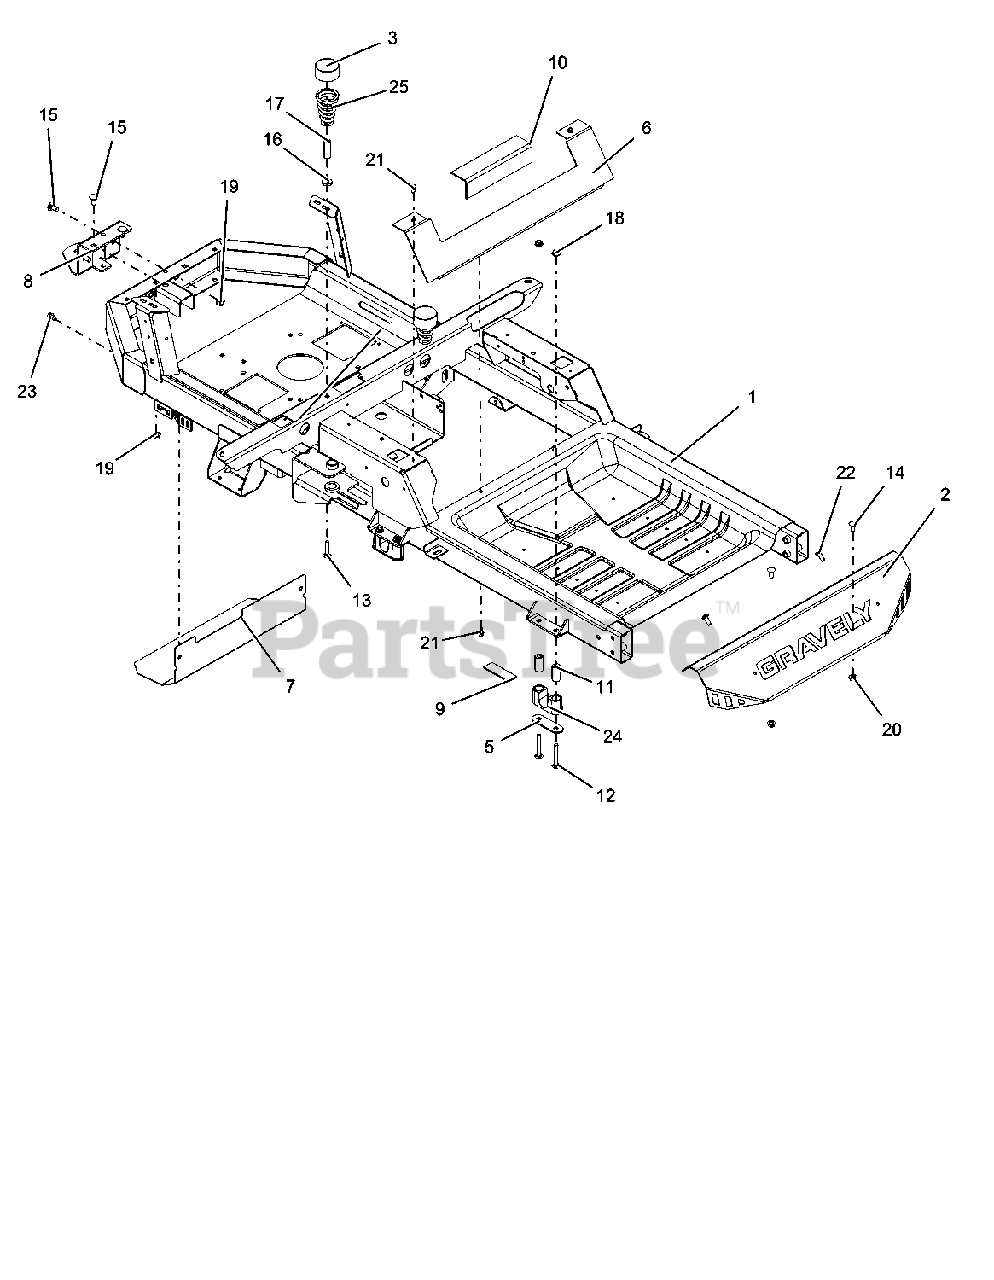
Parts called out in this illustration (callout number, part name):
1	WLDMT, FRAME IKON/ZTX
2	KIT, FOOTREST W/DECAL-ZTX
5	PLATE, BEARING SUPPORT
6	PLATE, SEAT KICK
7	HEAT, SHIELD
8	BRKT, HITCH-RED
9	PAD, RBR 1.0"X3.0" W/ADHESIVE
10	PAD, RBR -TANK
11	SPCR, SLV .323X.448X1.403
12	BLT-RDHDSQSHNK .31-18X2.25 YWZC
13	BLT-RDHDSQNK .31-18X1.50 G5 YWZC
14	BLT-RDHDSQNK .31-18X.75 G5 YWZC
15	BLT-RDHDSQNK .38-16X.75 G5 YWZC
16	WSHR-FL-STL, .328X.87X.179 YWZC
17	NUT, COUPLER 5/16-18 x 1.75
18	NUT, LK-CTR-FLG .31-18 YWZC
19	NUT, LK-TOP-FLG .38-16 YWZC
20	NUT, LK-TOP-FLG .312-18 YWZC
21	SCR-TAP .25-20X.50 HWH TR YWZ
22	SCR-TAP 10-24X.25 CRSLPH TR YZ
23	SCR-TAP .31-18X.50 HWH TR YWZ
24	BSHG, DECK LIFT PIVOT
25	SPRG, COMPRESSION
